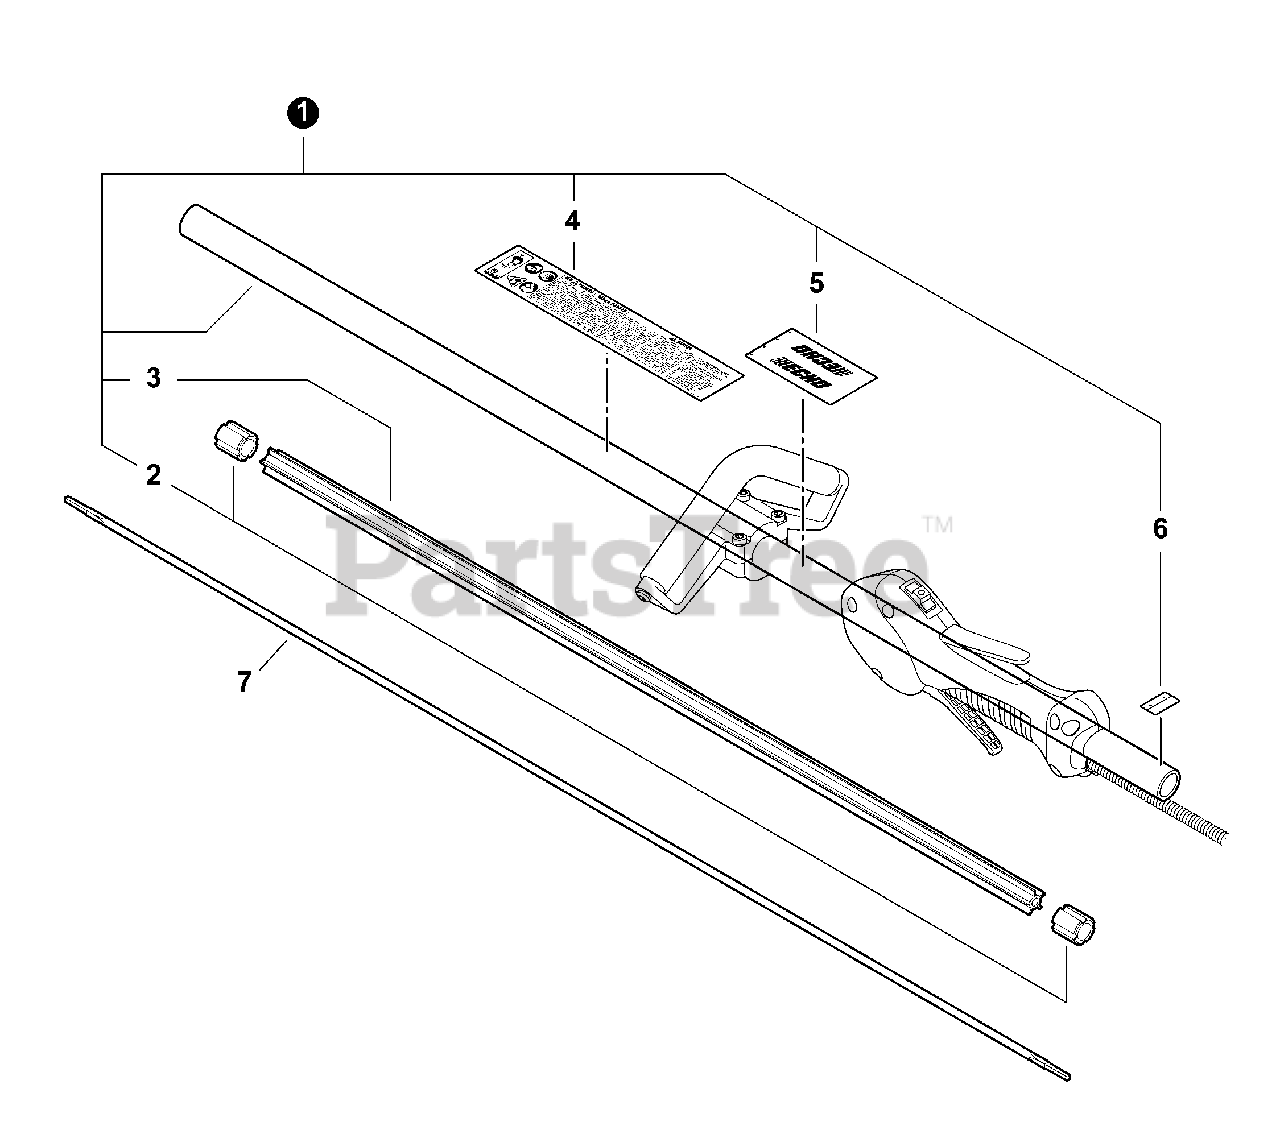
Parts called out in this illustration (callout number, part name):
1	MAIN PIPE ASSY
3	LINER, FLEXIBLE 21.6×1420
4	LABEL, CAUTION
5	LABEL, HANDLE LOCATION
6	LABEL - ALIGNMENT
7	DRIVESHAFT - FLEXIBLE
